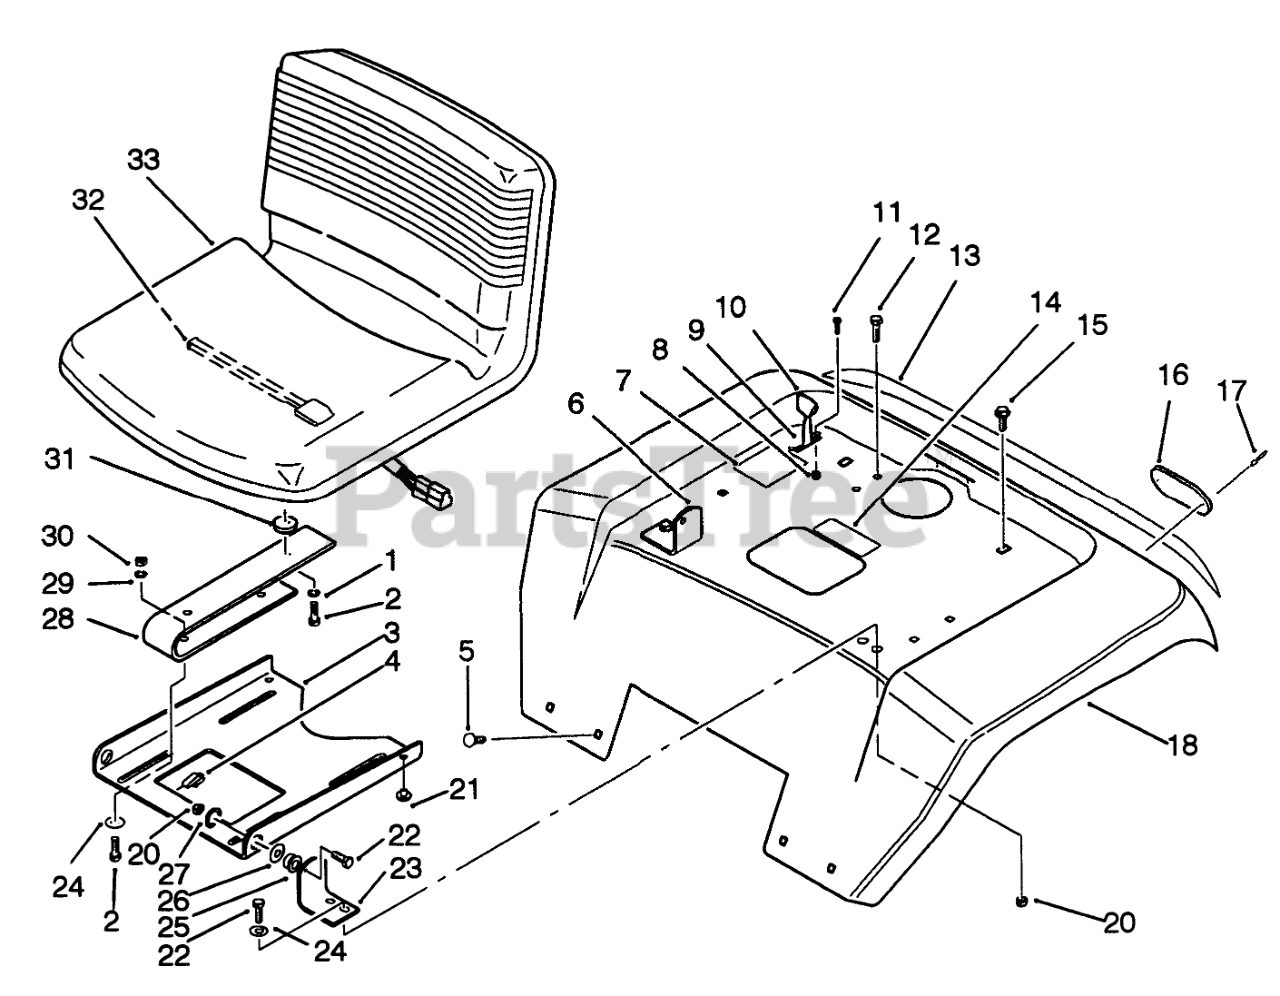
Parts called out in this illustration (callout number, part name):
1	Lockwasher
2	SCREW-HH
3	Plate-SeatPivot
4	J-CLIP
5	SCREW-CARR
6	Bracket-Pivot RH
7	DECAL-PUSH
8	Nut
9	CONTROL-PUSH VALVE
10	KNOB-THROTTLE
11	SCREW
12	Screw-Hex Hd.
13	DECAL-FENDER
14	DECAL-DANGER
15	Screw
16	Reflector
17	Poprivet
18	WLDMT-FENDER R
21	BUMPER-RUBBER
22	SCREW-HH
23	BRKT-PIVOT L.H. B
24	WASHER-PLAIN
25	BUSHING
26	WASHER-SPECIAL
27	WASHER-SPRING
28	Seat Spring
29	WASHER-PLAIN
30	NUT-LOCK, NI
31	SPACER-NYLON
32	SWITCH-SEAT
33	SEAT V-510
